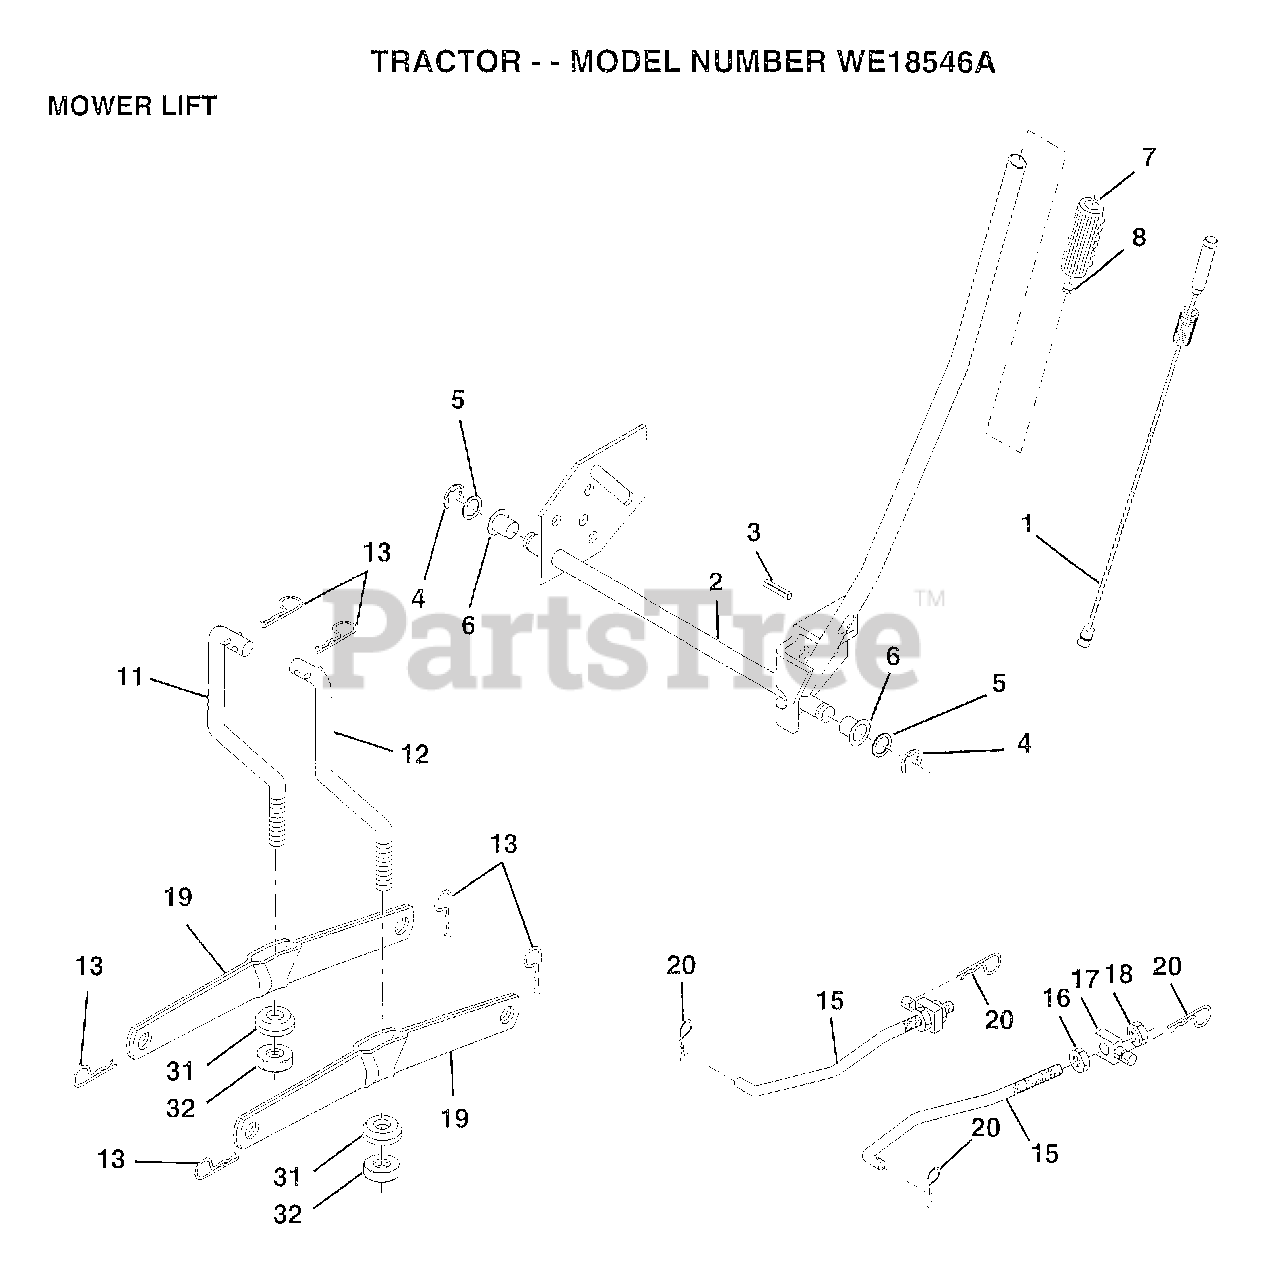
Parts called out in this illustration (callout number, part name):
1	WIRE ASM W.SPRING
2	"SHAFT ASM LIFT,RH"
3	PIN-GROOVE LT
5	WASHER
6	NYLON BEARING
7	GRIP
15	LINK.FRONT
16	NUT
17	TRUNION
18	NUT LTV
19	ARM SUSP REAR
20	RETAINER SPRING
31	BEARING PVT LH
32	NUT.CROWNLOCK.3/8
